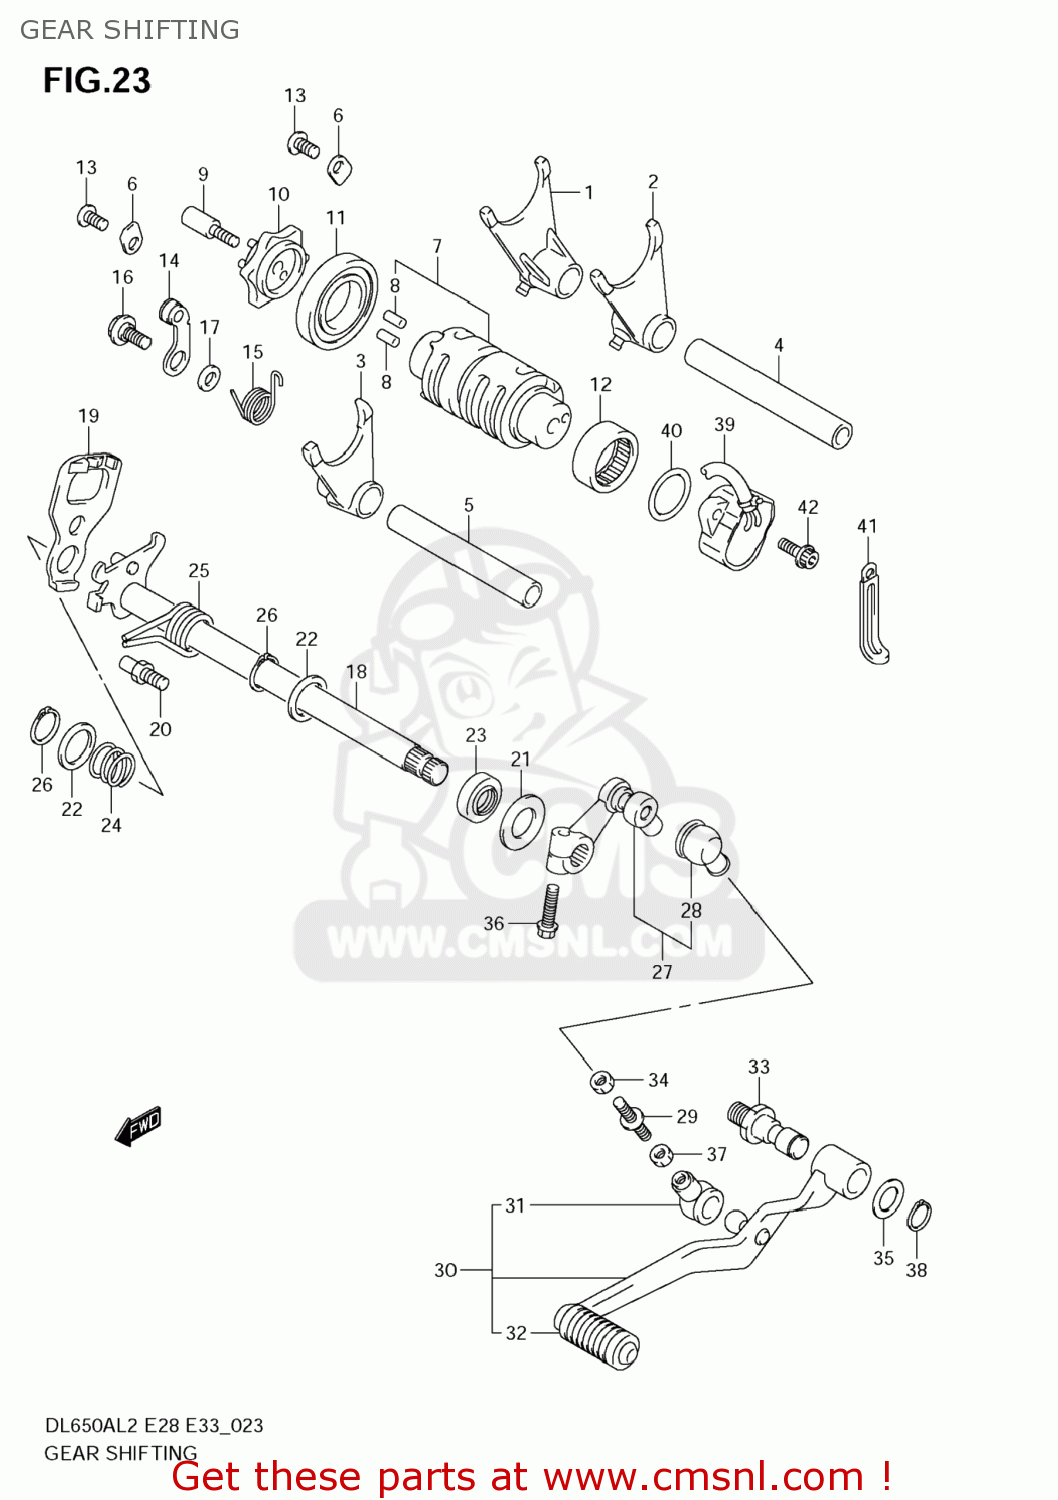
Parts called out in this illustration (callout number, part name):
1	FORK,GEAR SHIFT NO.1
2	FORK,GEAR SHIFT NO.2
3	FORK,GEAR SHIFT NO.3
4	SHAFT,GEAR SHIFT FORK
5	SHAFT,GEAR SHIFT FORK NO.1
6	RETAINER
7	CAM,GEAR SHIFT
8	PIN
9	BOLT,GEAR SHIFT CAM PLATE
10	PLATE,GEAR SHIFT CAM
11	BEARING(25X47X8)
12	BEARING(25X32X12)
13	SCREW
14	STOPPER,SHIFT CAM
15	SPRING,SHIFT
16	BOLT(6X14.3)
17	WASHER
18	SHAFT,GEAR SHIFT
19	PLATE,GEAR SHIFT CAM DRIVE
20	STOPPER,GEAR SHIFT ARM
21	WASHER(14X29X0.8)
22	SHIM(14X22X1)
23	SEAL,OIL(14X22X7.3)
24	SPRING
25	SPRING
26	CIRCLIP
27	ARM,GEAR SHIFT LINK
28	COVER,DUST
29	ROD,GEAR SHIFT LINK
30	LEVER ASSY,GEAR SHIFT
31	COVER,DUST
32	RUBBER,GEAR SHIFT PEDAL
33	SHAFT,GEAR SHIFT LEVER
34	NUT
35	WASHER(12.5X20X1)
36	BOLT
37	NUT
38	CIRCLIP
39	SENSOR ASSY,GEAR POSITION
40	O RING(D:2.4,ID:26.2)
41	CLAMP(L:80)
42	BOLT
